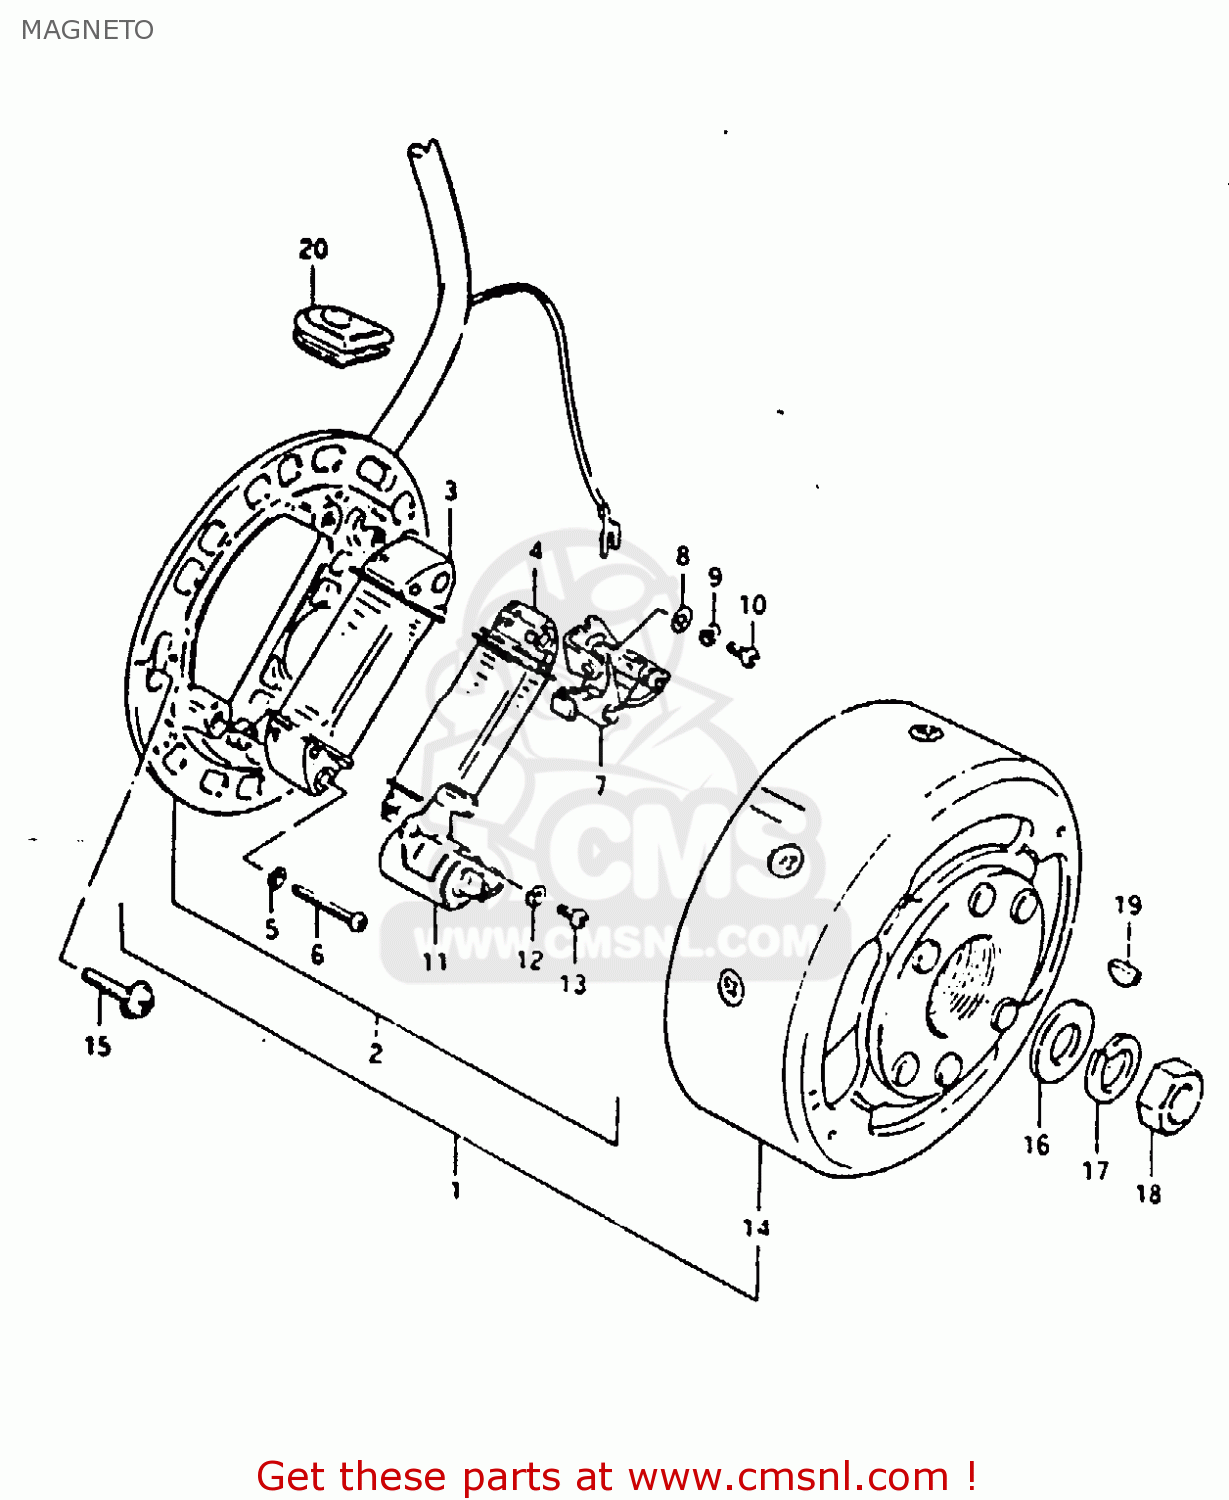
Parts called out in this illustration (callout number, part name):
1	MAGNETO ASSY
2	STARTER ASSY
3	COIL,LIGHTING
4	COIL,PRIMARY
5	LOCK WASHER
6	SCREW (4X30)
7	POINT ASSY,CONTACT
8	WASHER
9	LOCK WASHER
10	SCREW(4X10)
11	CONDENSER
12	LOCK WASHER
13	SCREW
14	ROTOR
15	SCREW(5X14)
16	WASHER
17	LOCK WASHER
18	NUT (10MM)
19	KEY
20	GROMMET
